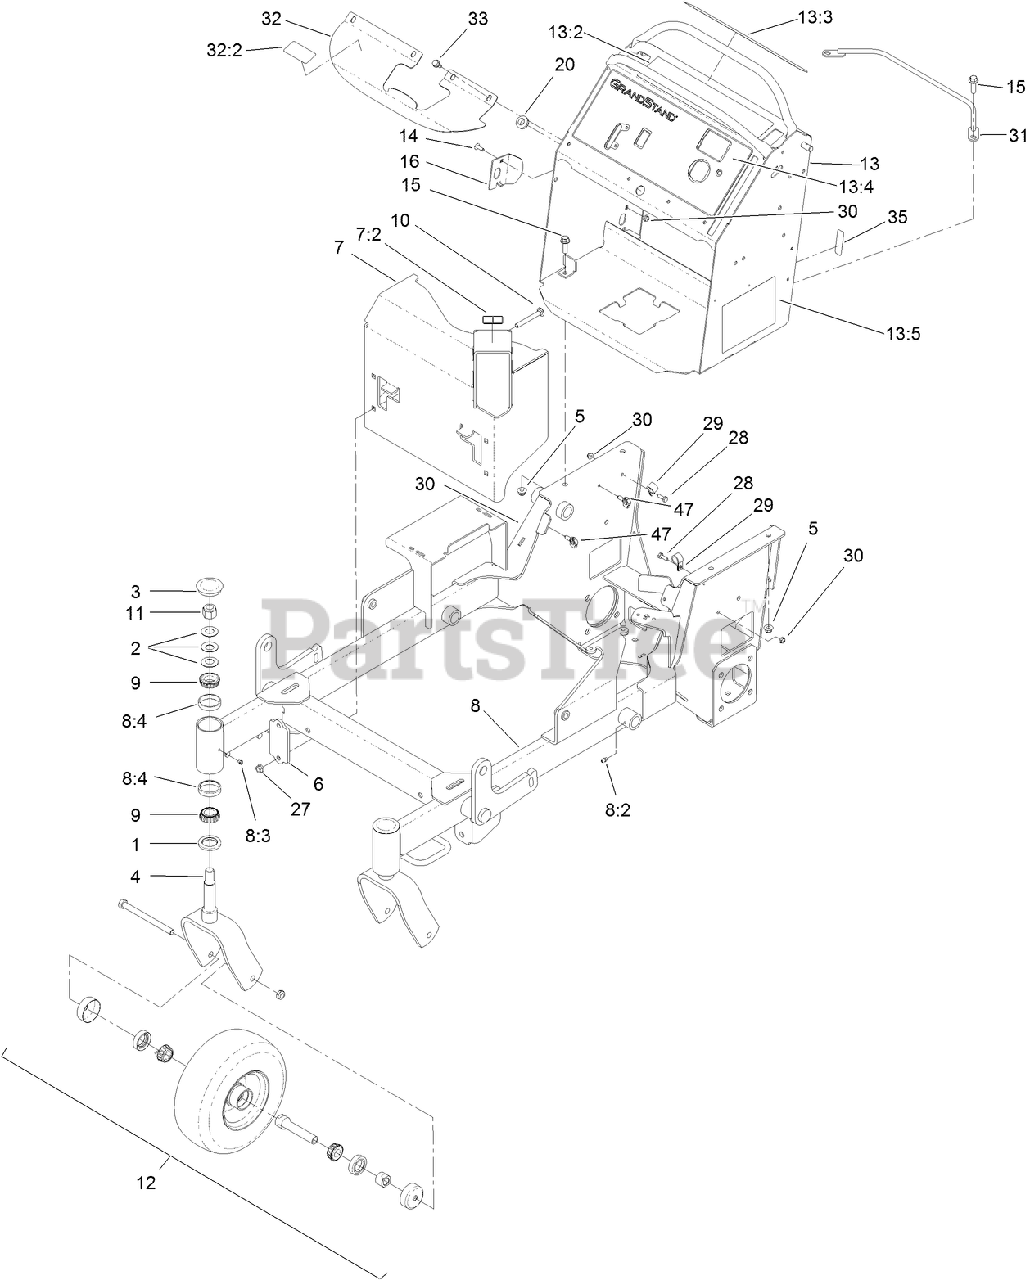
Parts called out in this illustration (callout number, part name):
1	SEAL-GREASE
2	WASHER-BELLVILLE
3	CAP-GREASE
4	FORK-CASTER
5	NUT-HF, NI
6	BRACKET-MOUNTING, GUARD
7	MUFFLER GUARD ASM
7:2	DECAL-WARNING
8	FRAME ASM
8:2	FITTING-GREASE
8:4	CUP-BEARING
9	BEARING-ROLLER, TAPERED
10	SCREW-CARR
11	NUT-LOCK, NI
12	WHEEL/TIRE AND BEARING ASM
13	CONTROL TOWER ASM
13:2	DECAL-OPC
13:3	DECAL-WARNING
13:4	DECAL-PANEL, CONTROL
13:5	DECAL-SERVICE
14	BOLT-CARR
15	SCREW-HHF
16	PLATE-STRIKER
20	GROMMET
27	NUT-HF
28	SCREW-HH
29	CLAMP-CABLE
30	NUT-HF
31	RETAINER-CABLE
32	COVER-TANK
32:2	DECAL-FILL, FUEL
33	SCREW-HWHTF
35	DECAL-FUSE
47	CLIP-HARNESS
